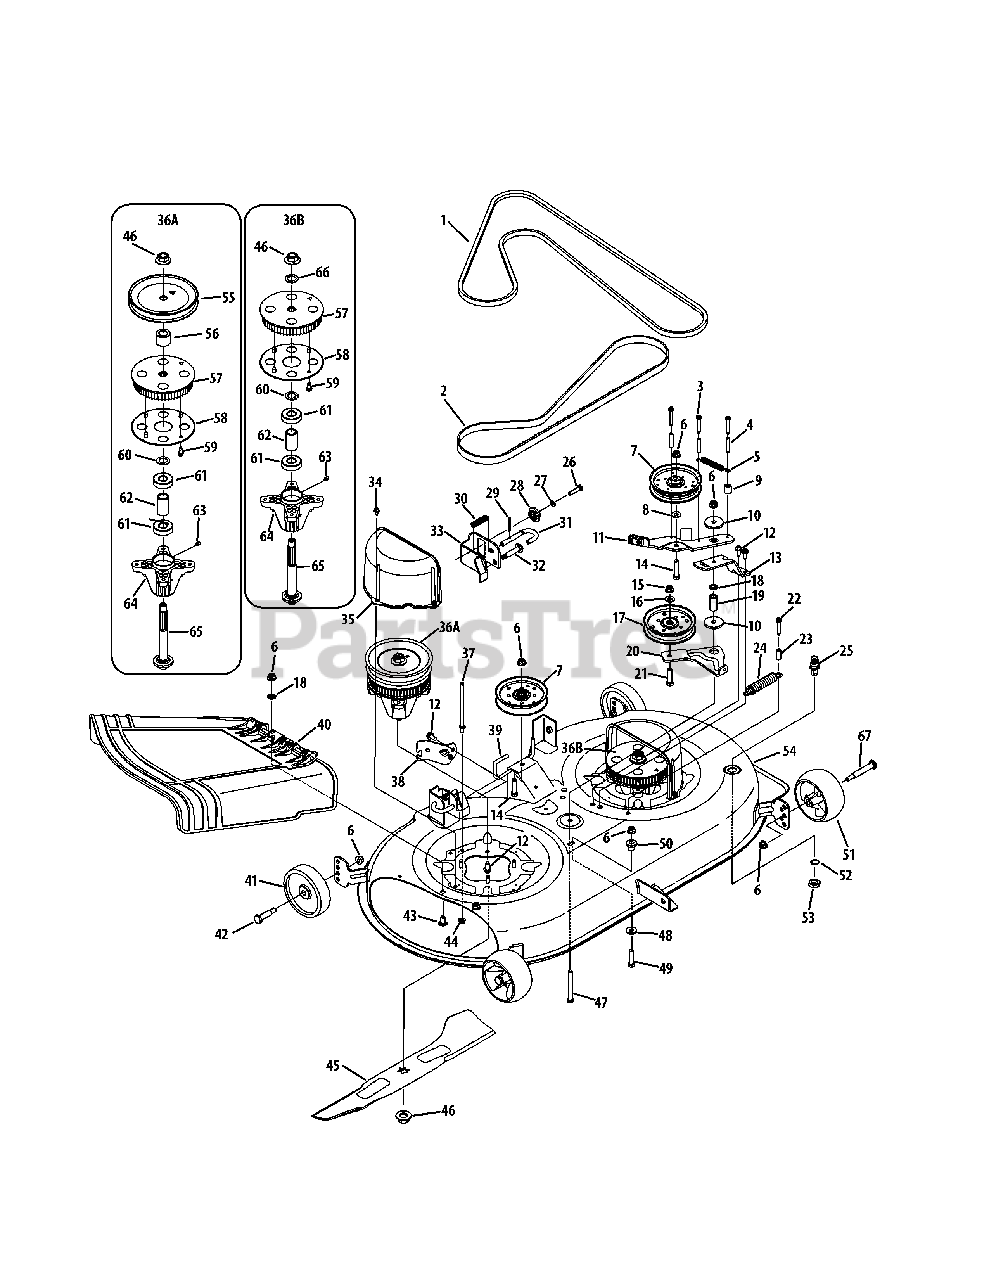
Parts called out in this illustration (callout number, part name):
1	Drive Belt
2	Timing Belt
3	Hex Washer Screw, 1/4-20 x 1.625
4	Spacer, .260 x .372 x 1.420
5	Extension Spring, .50 x 4.35
6	Flange Lock Nut, 3/8-16
7	Idler Pulley
8	Flat Washer, .406 x .875 x .105
9	Spacer, .385 x .625 x .700
10	Shoulder Spacer, .8840 x .190
11	Brake Assembly
12	Hex Washer Screw, 5/16-18 x .750
13	Idler Brace Bracket
14	Hex Screw, 3/8-16 x 1.75
15	Jam Lock Nut, 3/8-16
16	Flat Washer, .406 x .875 x .059
17	Idler Pulley
18	Push Nut, 3/8
19	Spacer, 3/8 x .68 x 1.46
20	Tension Bracket
21	Hex Screw, 3/8-16 x 1.50
22	Hex Washer, 1/4-20 x 1.625
23	Spacer, .260 x .375 x 1.030
24	Extension Spring, .865 x 4.68
25	Deck Water Nozzle
26	Hex Screw, 5/16-18 x 1.25
27	Lock Washer, 5/16
28	Deck Adjustment Gear
29	Cotter Pin, 1/8 x 1.25
30	Compression Spring, .531 x 1.75
31	Deck Handle Rod
32	Shoulder Bolt, 5/16-24 x .435 x 1.76
33	Deck Lift Bracket
34	Hex Washer Screw, 1/4-20 x .500
36A	Spindle Assembly, Drive
36B	Spindle Assembly, Driven
37	Belt Guard Pin
38	Deck Engage Cable Bracket
39	Belt Keeper Rod
40	Chute Assembly
41	Deck Wheel
42	Shoulder Screw, 3/8-16 x .496 x 1.525
43	Carriage Bolt, 3/8-16 x .75
44	Flange Lock Nut, 5/16 x 18
45	2-in-1 Blade
46	Flange Nut, 5/8-18
47	Hex Screw, 3/8-16 x 3.25
48	Flat Washer, .385 x 1.0 x .135
49	Hex Screw, 3/8-16 x 1.25
50	Shoulder Spacer, 1.38 x .445 x .36
51	Deck Wheel
52	Lock Washer, 5/8
53	Hex Nut, M16-1.5
54	Deck Assembly
55	Pulley (Drive Spindle)
56	Spacer, .792 x 1.060 x 1.860 (Drive Spindle)
57	Timing Pulley
58	Timing Pulley Plate
59	Screw, 1/4-10 x .625
60	Flat Washer, .793 x 1.24 x .06
61	Ball Bearing, .787 x 1.85 x .551
62	Spacer, .792 x 1.060 x 1.860
63	Drive Lube Fitting
64	Spindle Housing
65	Spindle Shaft (Drive Spindle)
65	Spindle Shaft (Driven Spindle)
66	Flat Washer, .760 x 1.50 x .120
67	Shoulder Bolt .50 x 2.5 x 3/8-16
